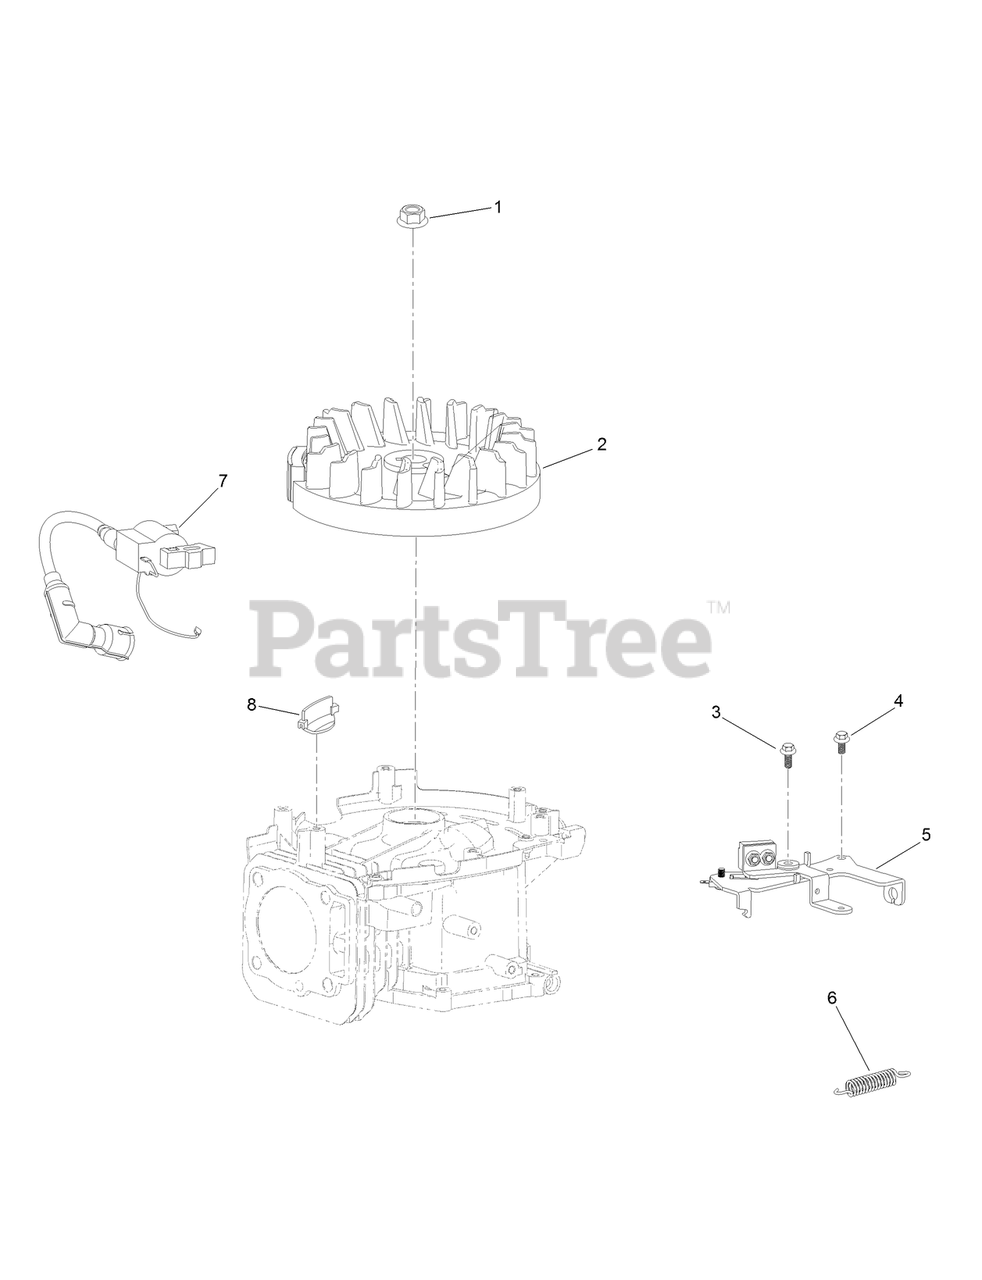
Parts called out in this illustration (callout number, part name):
1	NUT-FLANGE
2	FLYWHEEL
3	BOLT-FLANGE
4	SCREW-HHF
5	BRAKE ASM
6	SPRING-BRAKE
8	GUARD-FLYWHEEL
